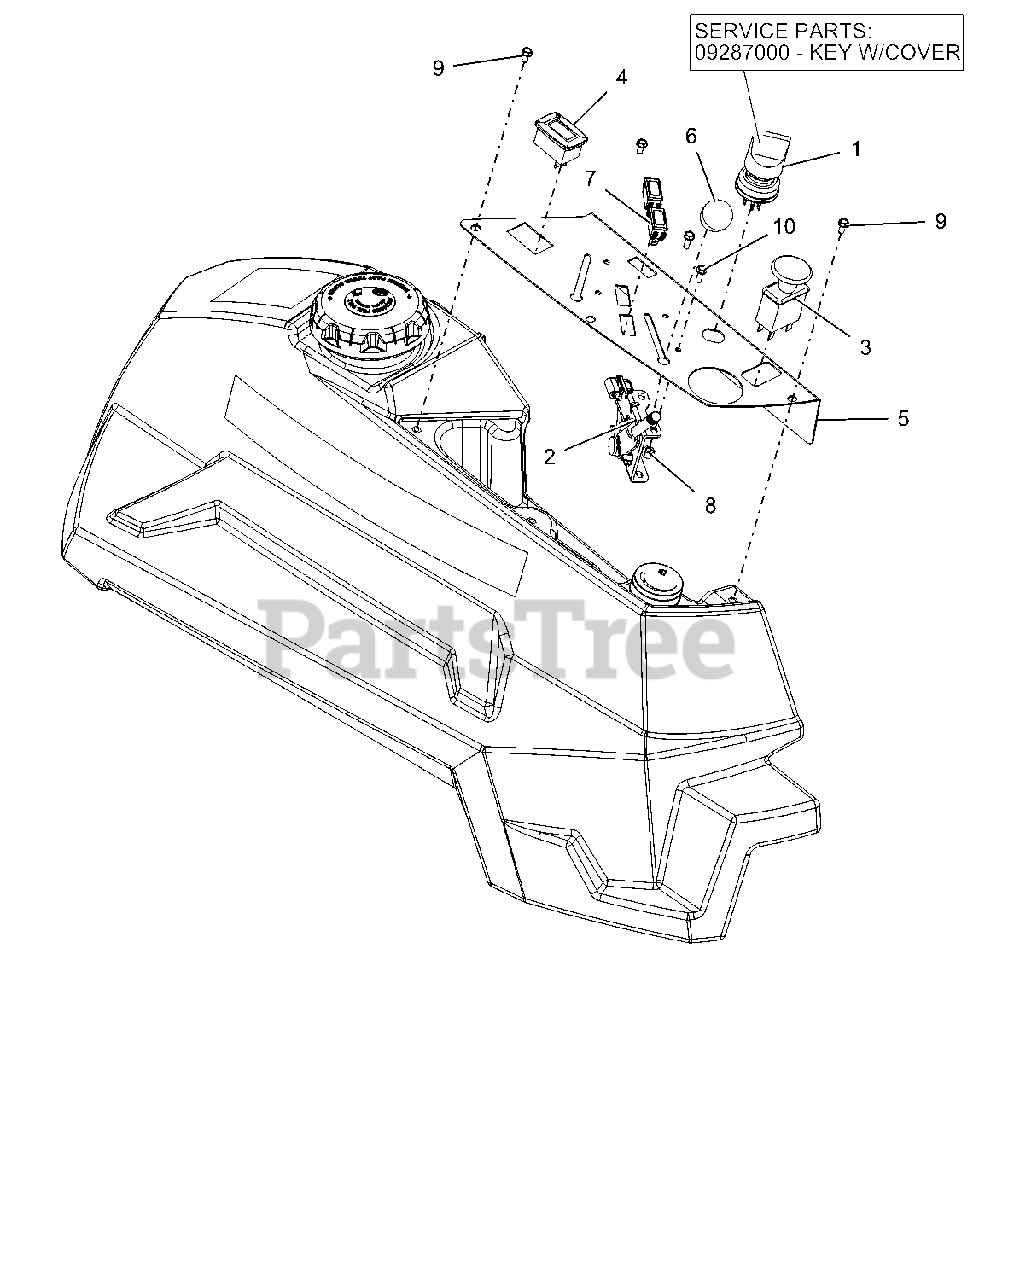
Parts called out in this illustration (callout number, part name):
1	KEY, W/ SHIELD
1	SWITCH, IGNITION
2	CABLE, PRO-CTRL 35.50"
3	SWITCH, CLUTCH
4	METER, HOUR W/MAINTENANCE
5	PT400 CONTROL PANEL - RED
6	KNOB-CONTROL-BLACK .38-16X.50
7	LIGHT,INDICATOR
8	NUT-LK-NYL 10-24 W/INSRT YWZC
9	SCR-MCH 10-24X.38 HWHSTAINLESS
10	SCR-MCH 10-24X.50 HWH YWZC
